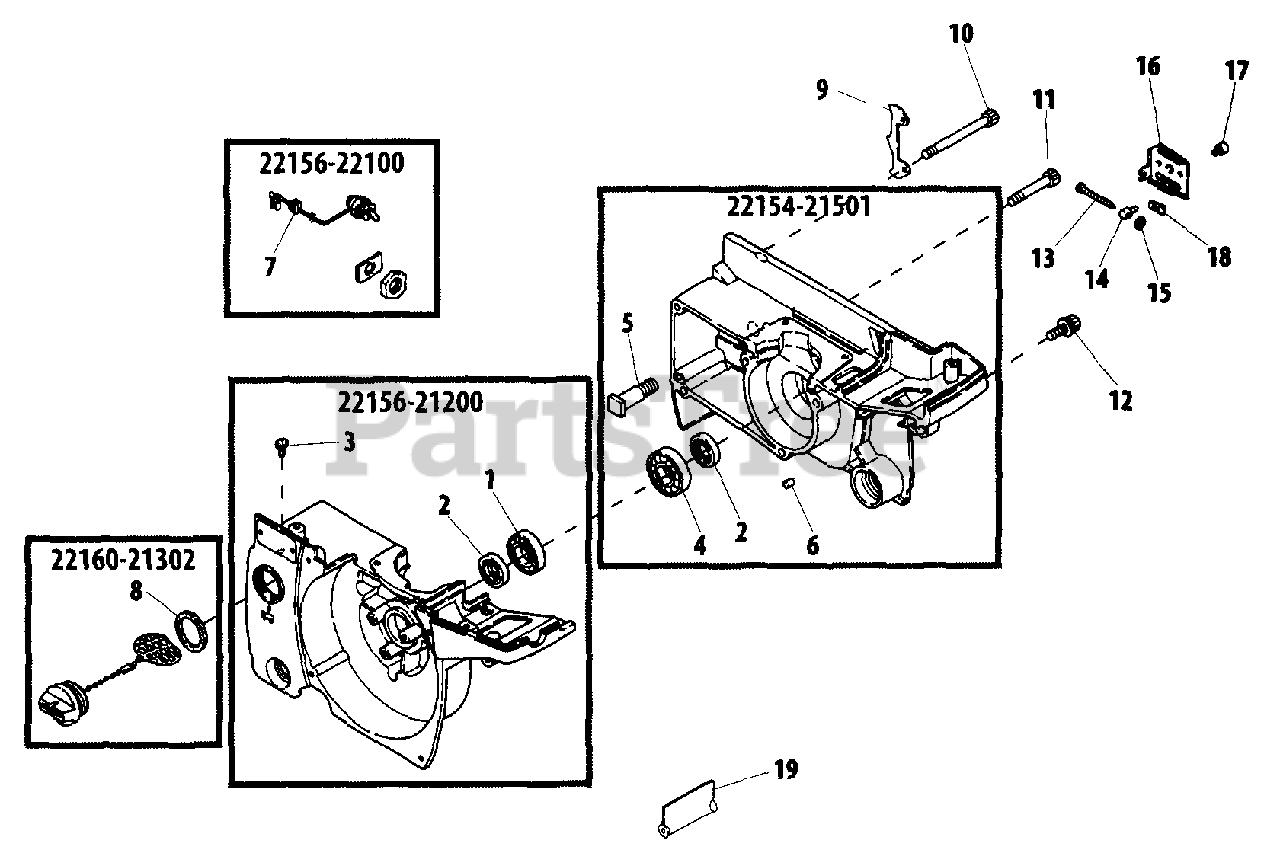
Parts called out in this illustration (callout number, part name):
1	BEARING, BALL 6001 C3
2	SEAL, OIL 12
3	VENT ASSY
4	BEARING, BALL 6201 C3
5	STUD, GUIDE BAR
6	PIN, LOCATING Ø4×8
8	GASKET, CAP
9	SPIKE, BUMPER
10	BOLT, ADHESIVE M5×45
11	BOLT, ADHESIVE M5×30
12	BOLT, ADHESIVE M5×18
13	SCREW, SLIDE
14	TENSIONER, CHAIN
15	NUT, PUSH
16	PLATE, GUIDE - INNER
17	SCREW
18	GUIDE, SLIDE SCREW GEAR
19	PLATE, SHUTTER
22154-21501	CRANKCASE ASSY - RIGHT
22156-21200	CRANKCASE ASSY - FRONT
22156-22100	SWITCH ASSY, ON-OFF
22160-21302	CAP ASSY, OIL
